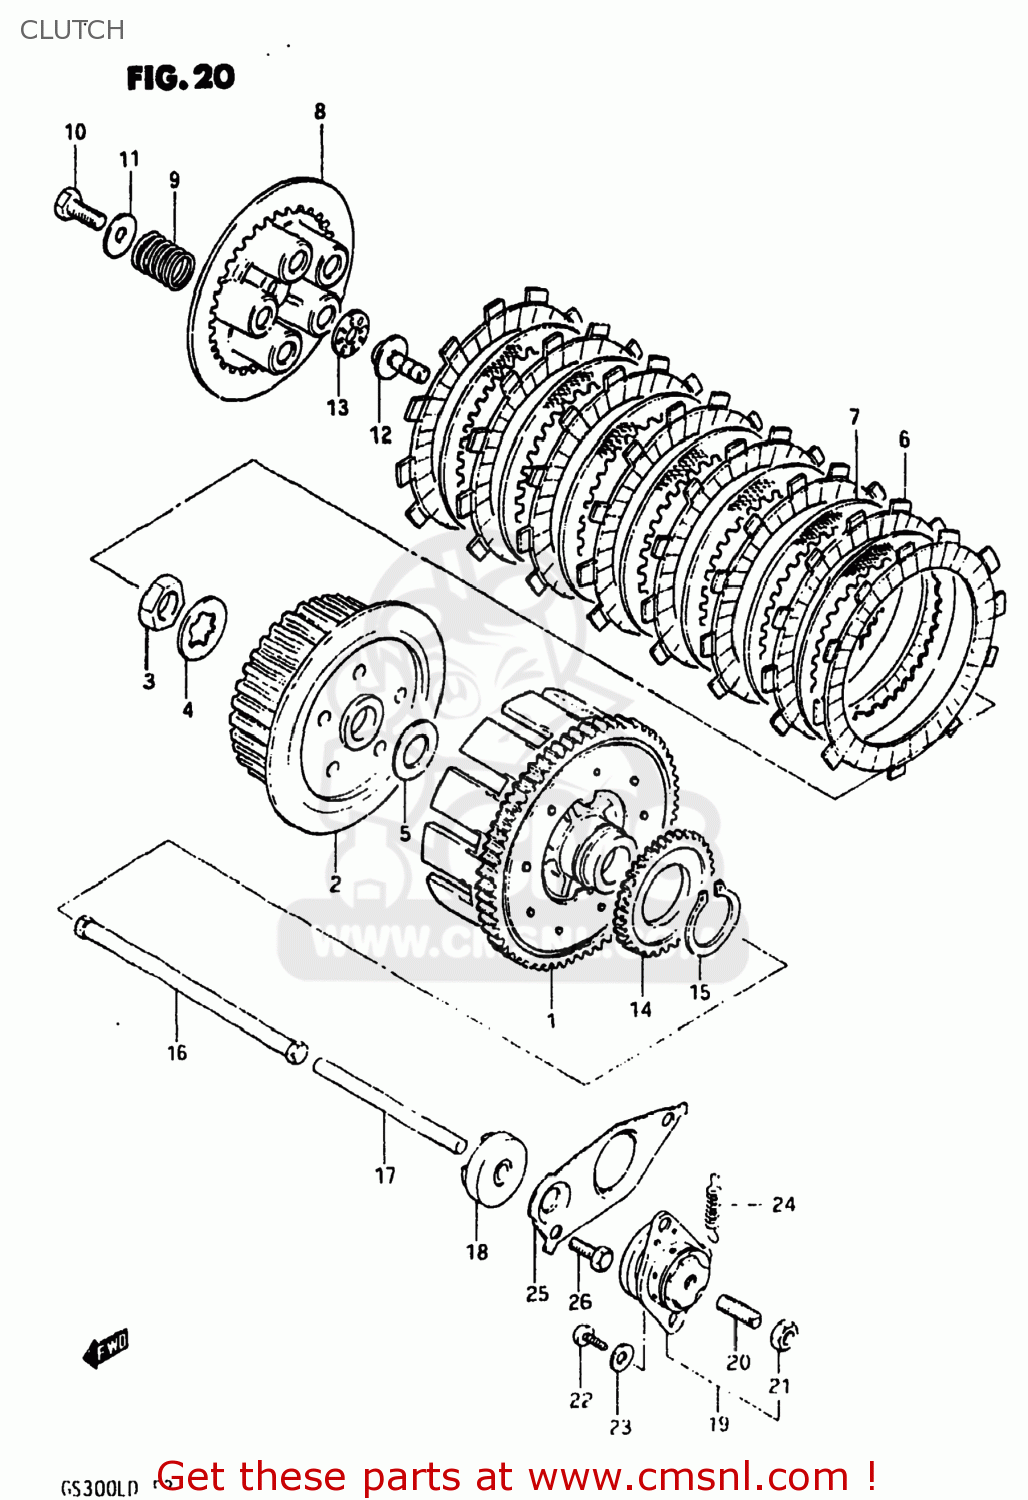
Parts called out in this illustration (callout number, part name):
1	GEAR ASSEMBLY,PRIMARY DRIVE
2	HUB,CLUTCH SLEEVE
3	NUT
4	WASHER
5	WASHER
6	PLATE,CLUTCH DRIVE (MCA)
7	PLATE,CLUTCH DRIVEN (NAS)
8	DISC,CLUTCH PRESSURE
9	SPRING
10	BOLT(5X16)
11	WASHER (5.5X16X1.2)
12	ROD,CLUTCH RELEASE
13	BEARING(10X22X2.8)
14	GEAR,OIL PUMP DRIVE
15	CIRCLIP
16	ROD,CLUTCH PUSH
17	ROD,CLUTCH PUSH
18	SEAL,OIL(6X31X10)
19	SCREW ASSY,CLUTCH RELEASE
20	SCREW
21	NUT 6MM
22	SCREW
23	WASHER
24	SPRING
25	PLATE,CLUTCH PUSH ROD
26	BOLT
